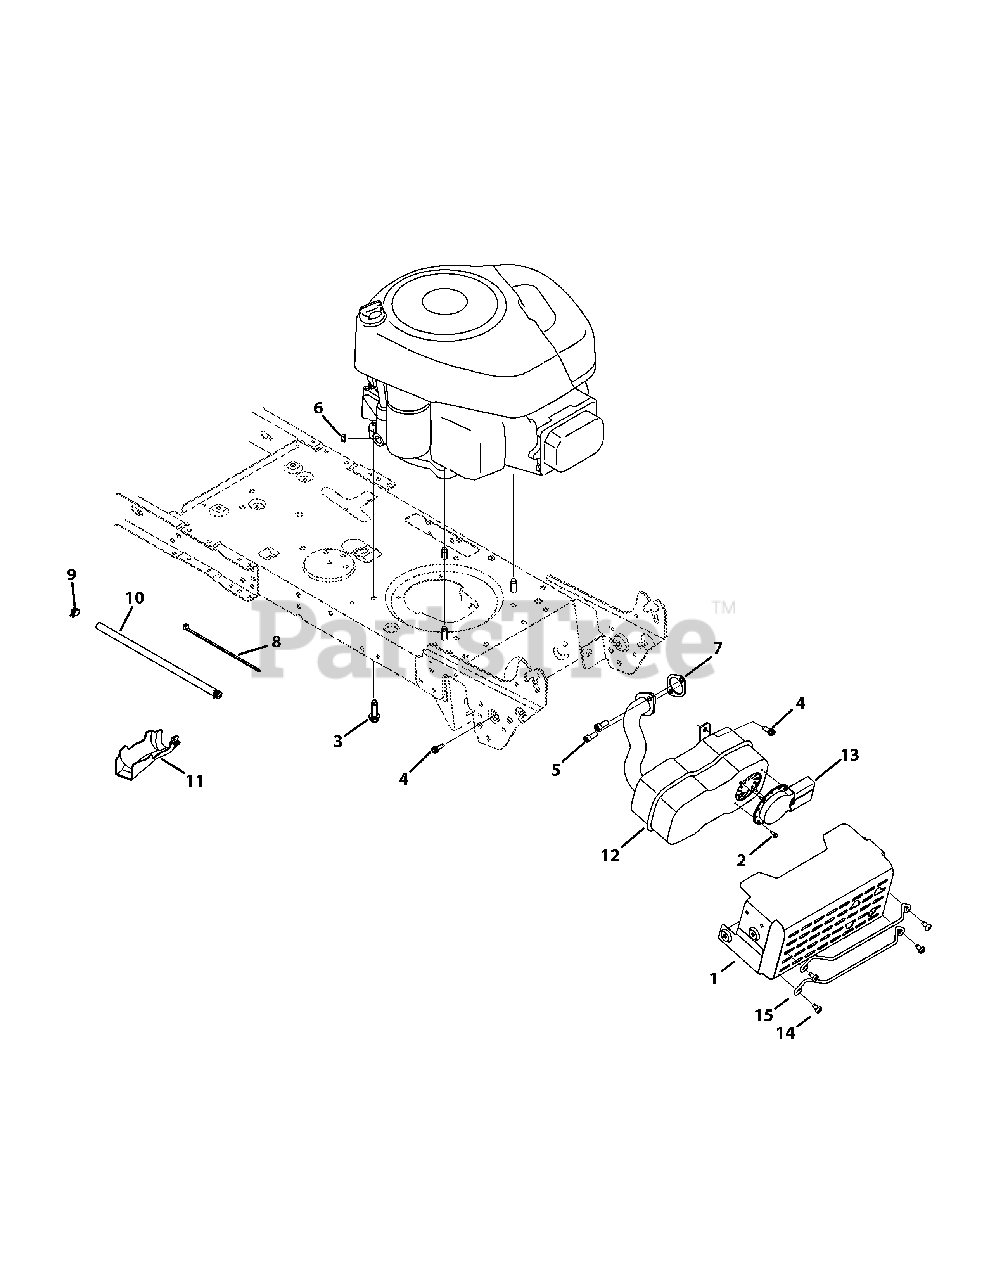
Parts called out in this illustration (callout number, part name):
1	Muffler Shield Assembly
2	Screw, 8-18 x .500
3	Screw, 3/8-16 x 1.0
4	Screw, 1/4-20 x .750
5	Socket Screw, 5/16-18 x .750
6	Sems Nut, 1/4-20
7	Exhaust Gasket, 10 HP Briggs
8	Cable Tie
9	Clamp Hose, .490 diameter
10	Fuel Hose, Low Permeation
11	Oil Drain Sleeve
12	Muffler, Single Inlet
13	Muffler Deflector Long
14	Pan Torx Screw 1/4
15	Muffler Guard Rod
